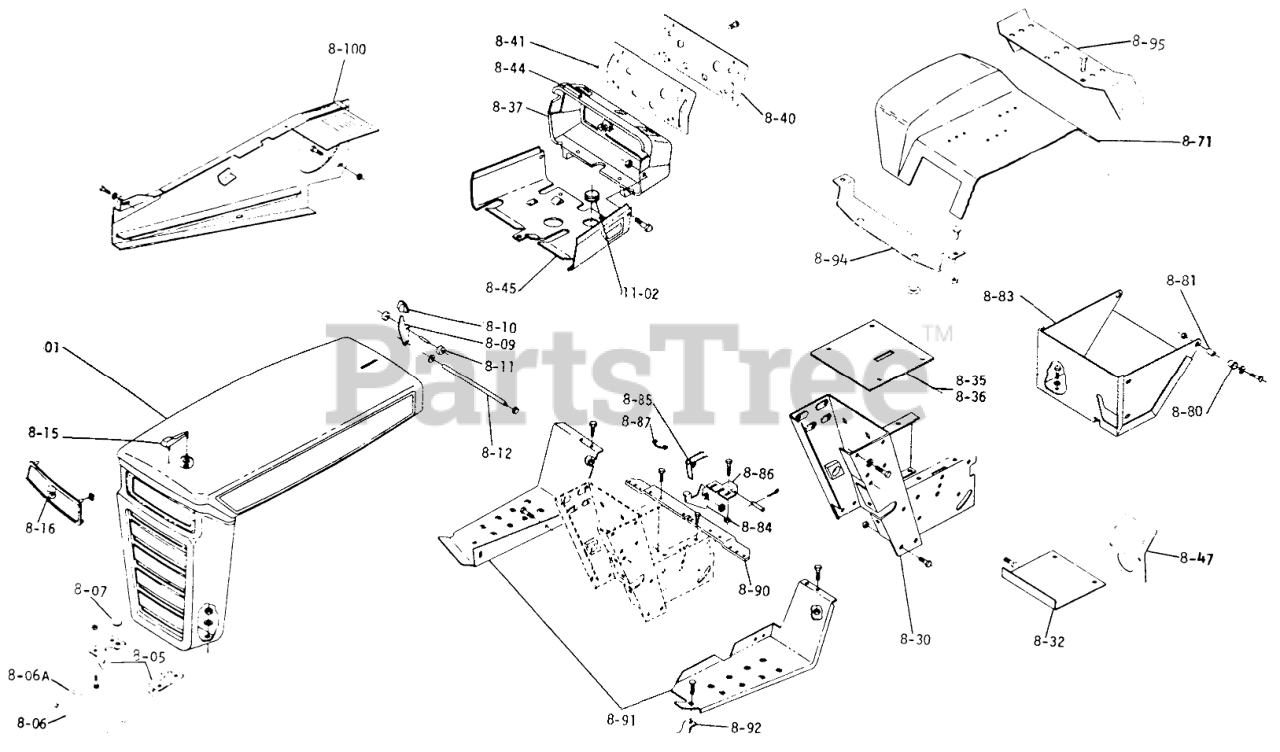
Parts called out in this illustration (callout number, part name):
8-01	Hood
8-05	GRILL PIVOT BRKT
8-06	GRILL PIVOT ROD
8-06A	ROD-HOOD STOP
8-07	GROMMET
8-09	LEVER HOOD LATCH
8-10	KNOB
8-11	Roller
8-12	Rod Latch
8-15	Hood Ornament
8-16	Plate-Escutcheon
8-30	Hoodstand Assy. (C10, C12, B14)
8-32	Cover-Dust
8-35	Plate-Cover-Instructions
8-36	Plate-Back up
8-37	Housing
8-40	Panel-Dash
8-41	BACK UP PLATE
8-44	Tape
8-45	Support-Fuel Tank
8-47	Instrument Backet
8-71	Fender
8-80	BUSHING-FLANGED
8-81	SPACER
8-83	Tool Box
8-84	Latch Fender
8-85	Spring
8-86	BRACKET FENDER LATCH
8-90	Bracket
8-91	Footrest R.H.
8-92	BRACKET
8-93	Bracket
8-94	Fender Bracket
8-95	Bracket Fender Hinge
8-100	Belt Guard
